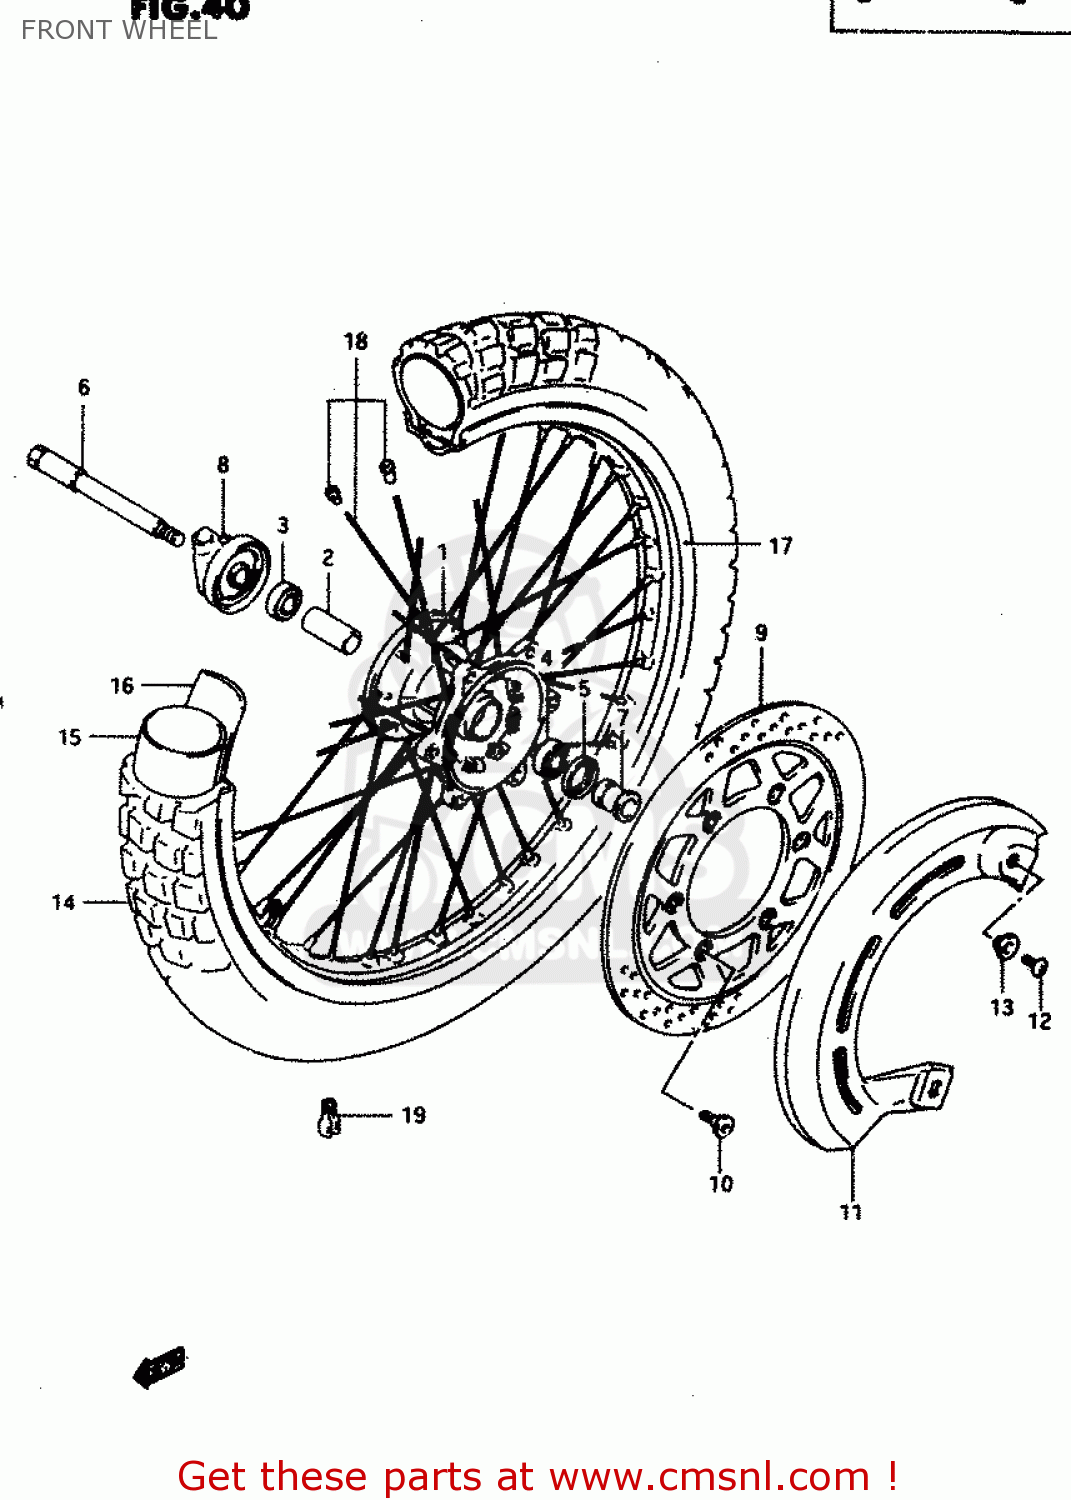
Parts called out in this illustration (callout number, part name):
1	HUB,FRONT WHEEL
2	SPACER,FR HUB BEARING
3	BEARING
4	BEARING
5	SEAL,OIL(22X35X5)
6	AXLE,FR
7	SPACER,FR AXLE,L
8	BOX ASSY,SPEEDOMETER GEAR
9	DISC,FR BRAKE
10	BOLT,BRAKE DISC
11	COVER,FR BRAKE DISC
12	SCREW 6X12
13	WASHER
14	TIRE,FRONT 90/90-21 54
15	TUBE
16	PROTECTOR,WHEEL INNER
17	RIM,FR WHEEL(21X1.85)
18	SPOKE SET,FR WHEEL
19	BALANCER,WHEEL
